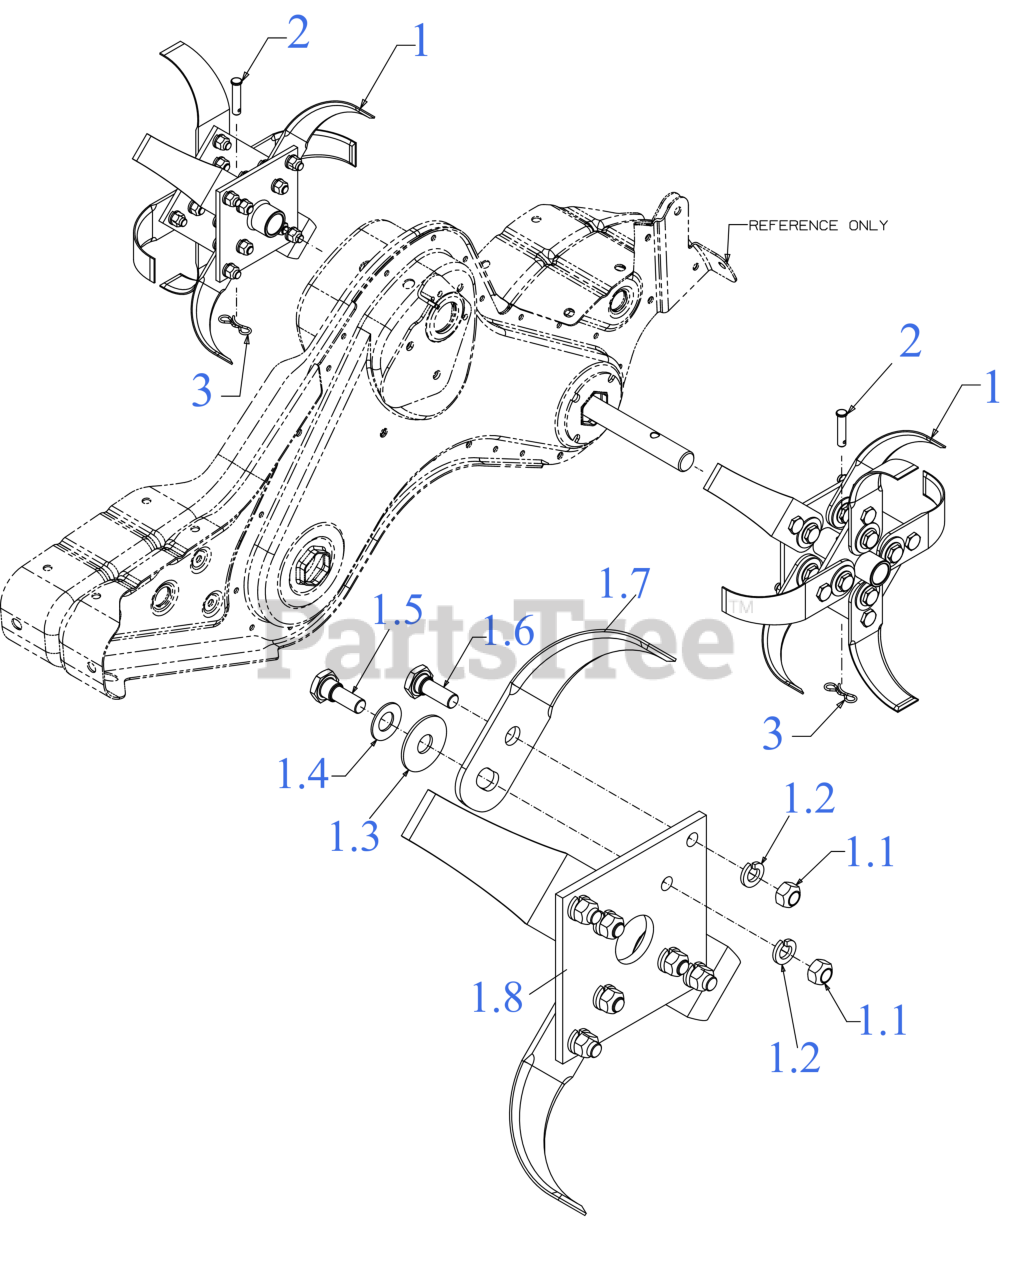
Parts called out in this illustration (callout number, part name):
1	TINE ASSEMBLY
1.1	HEX LOCK NUT 3/8-2
1.2	LOCK WASHER 3/8
1.3	WASHER .51 x 1.5 x .07
1.4	BELL WASHER
1.5	SHOULDER SCREW
1.6	SHOULDER SCREW 3/8-24 x 3/4 LG
1.7	ARTICULATING TINE (POWDER BLACK)
1.8	TINE ADAPTER ASSEMBLY
2	CLEVIS PIN .375 x .1.75
3	PIN:COTTER
